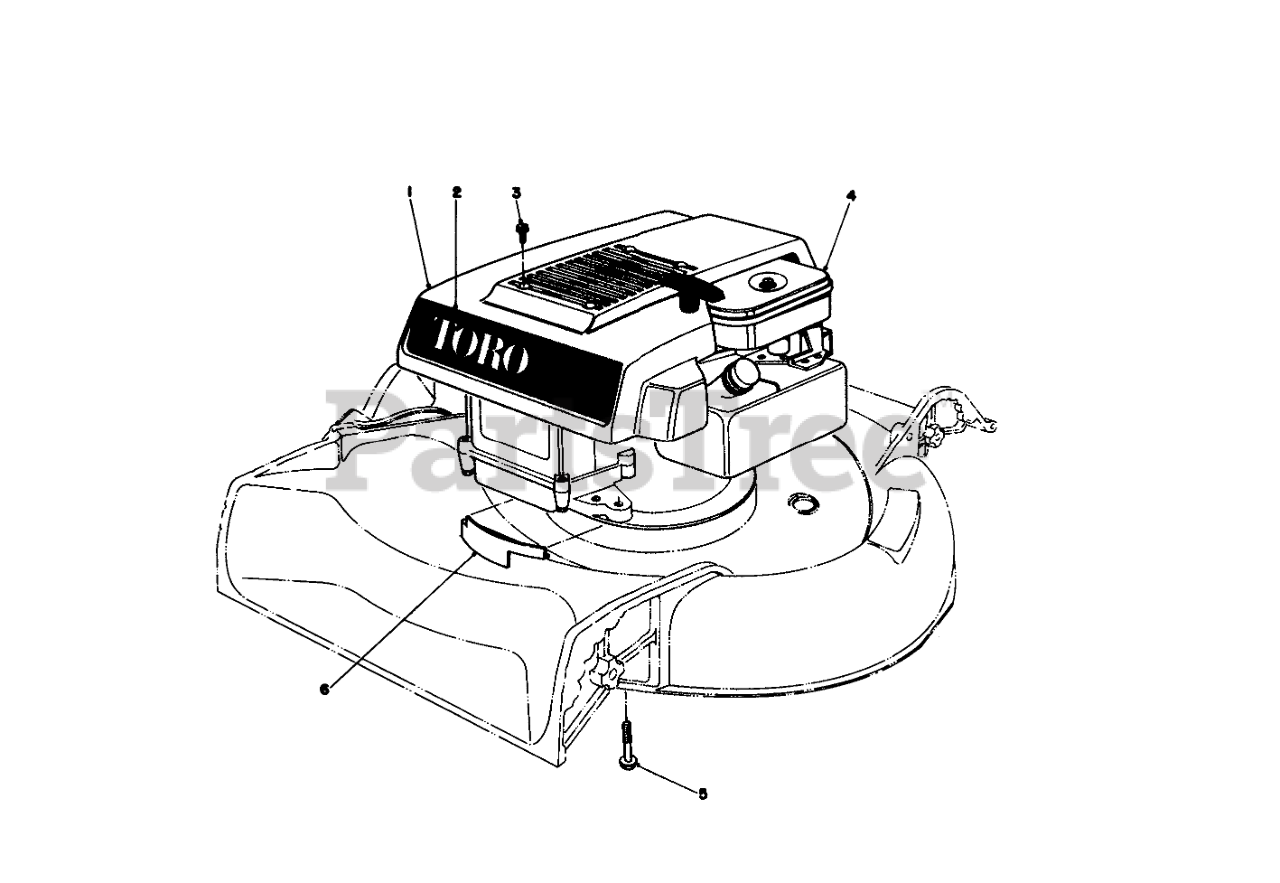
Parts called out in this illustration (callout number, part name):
1	SHROUD
2	Decal-Toro
3	8X1/2 SELF TAP SCREW
4	Engine (Model No. 16009)
5	3/8-16 X 2-3/4 CAPSCR
6	HOUSING CAP
